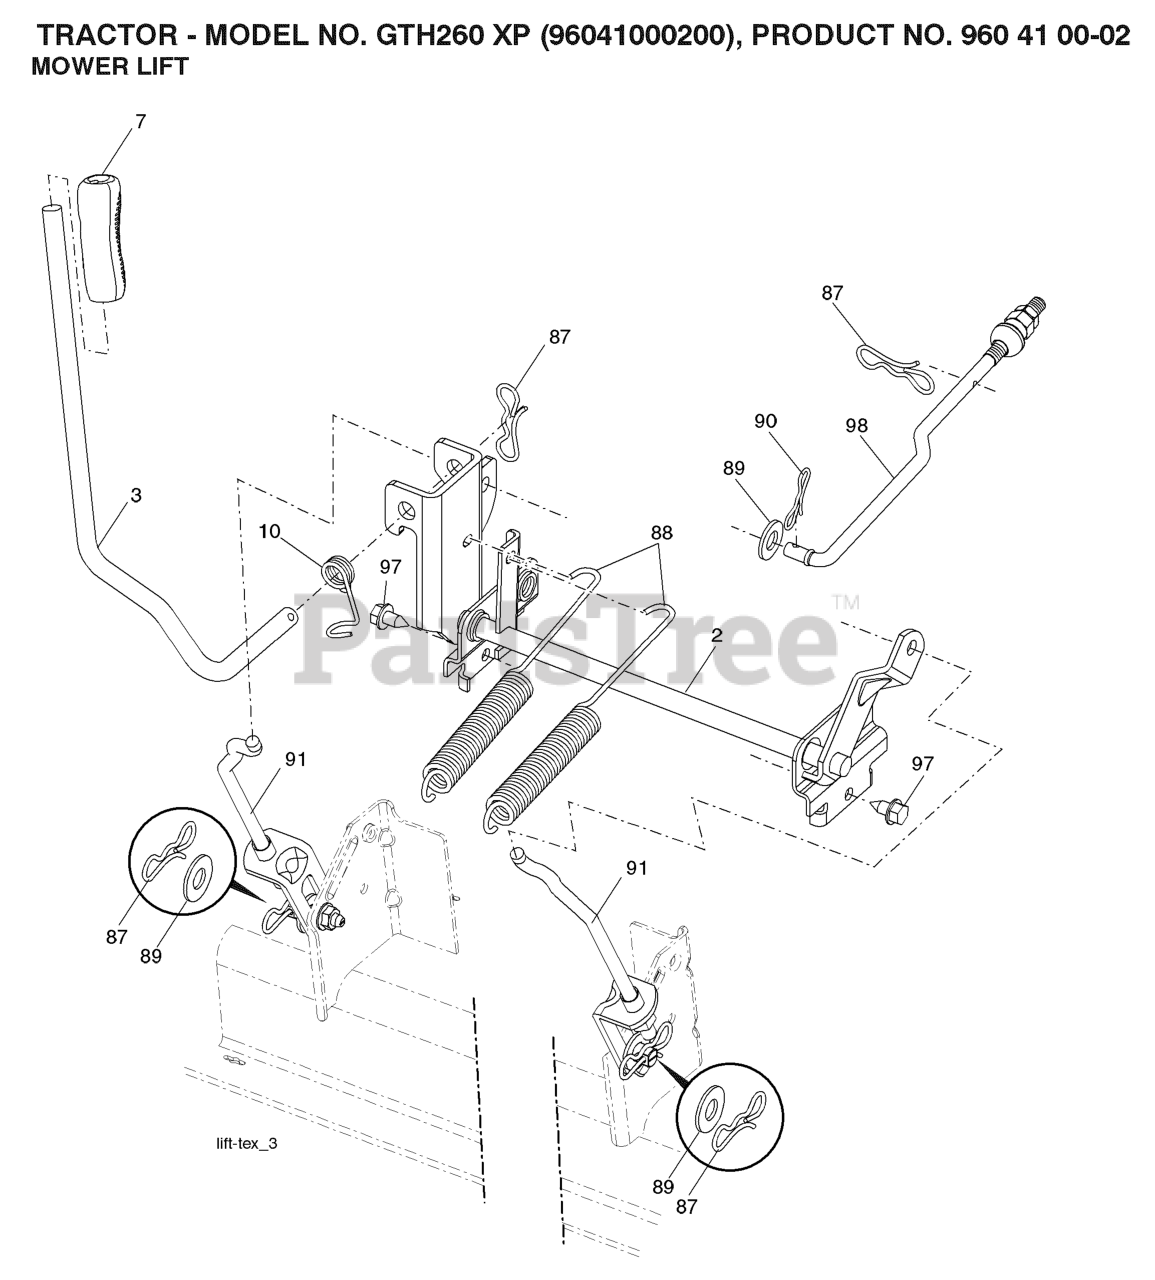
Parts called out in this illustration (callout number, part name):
2	SHAFT.ASM.LIFT.CROSS.H
3	LEVER.LIFT.HANDLE.GT
7	GRIP.LEVER.5625.ID
10	SPRING.TORSION.LIFT.HANDLE
87	PIN.COTTER.7/16.BOW TI.
88	SPRING.LIFT.ASSIST.GT2
89	WASHER.CLEAR.ZINC
90	PIN.COTTER.5/16.BOW TI
91	LINK.LIFT.ASM.REAR.GT.
97	SCREW 3/8-16X3/4
98	LINK.ASM.SUSP.FRONT.MWR.10.5
